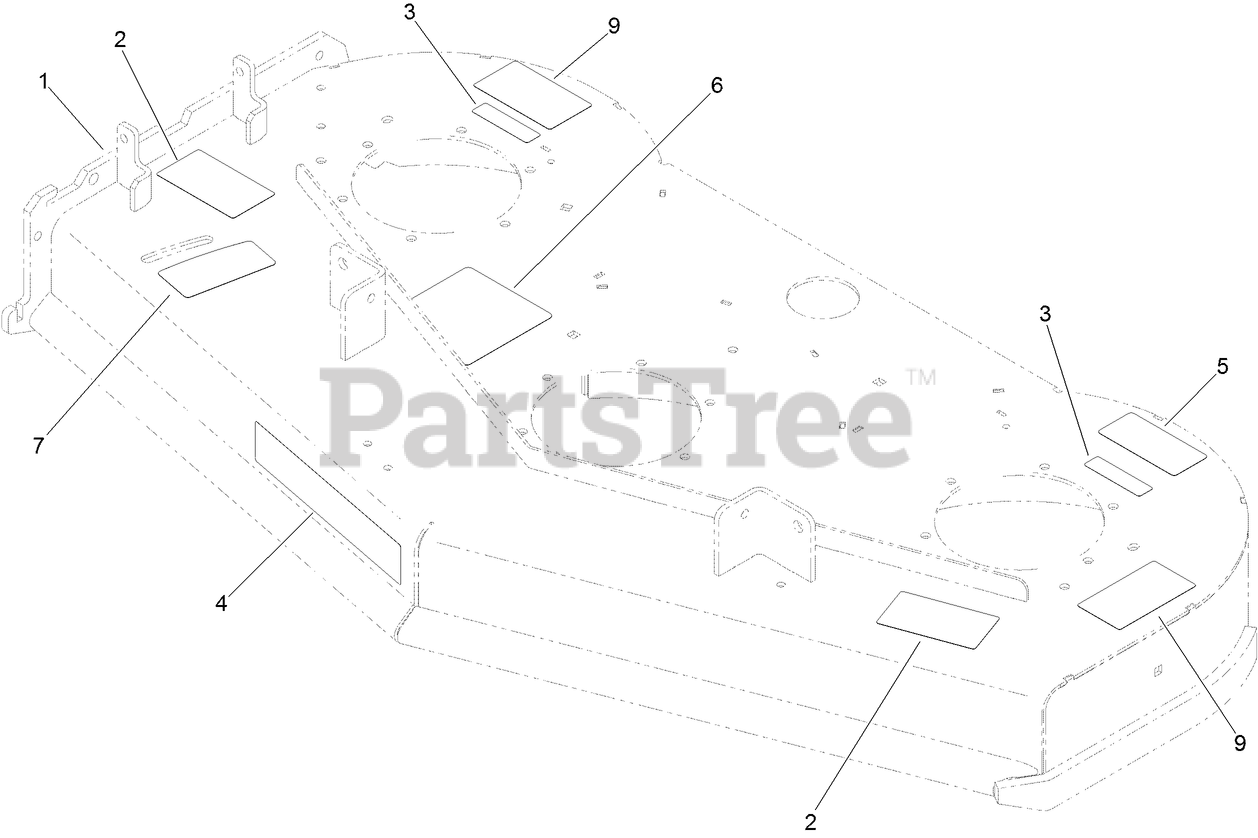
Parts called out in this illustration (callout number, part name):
1	DECK ASM
2	DECAL-DANGER
3	DECAL-DANGER
5	DECAL-TORQUE, BLADE BOLT
6	DECAL-BELT TENSION, CE
7	DECAL-ADJUSTMENT, BAFFLE
9	DECAL-DANGER, ROTATING PARTS
